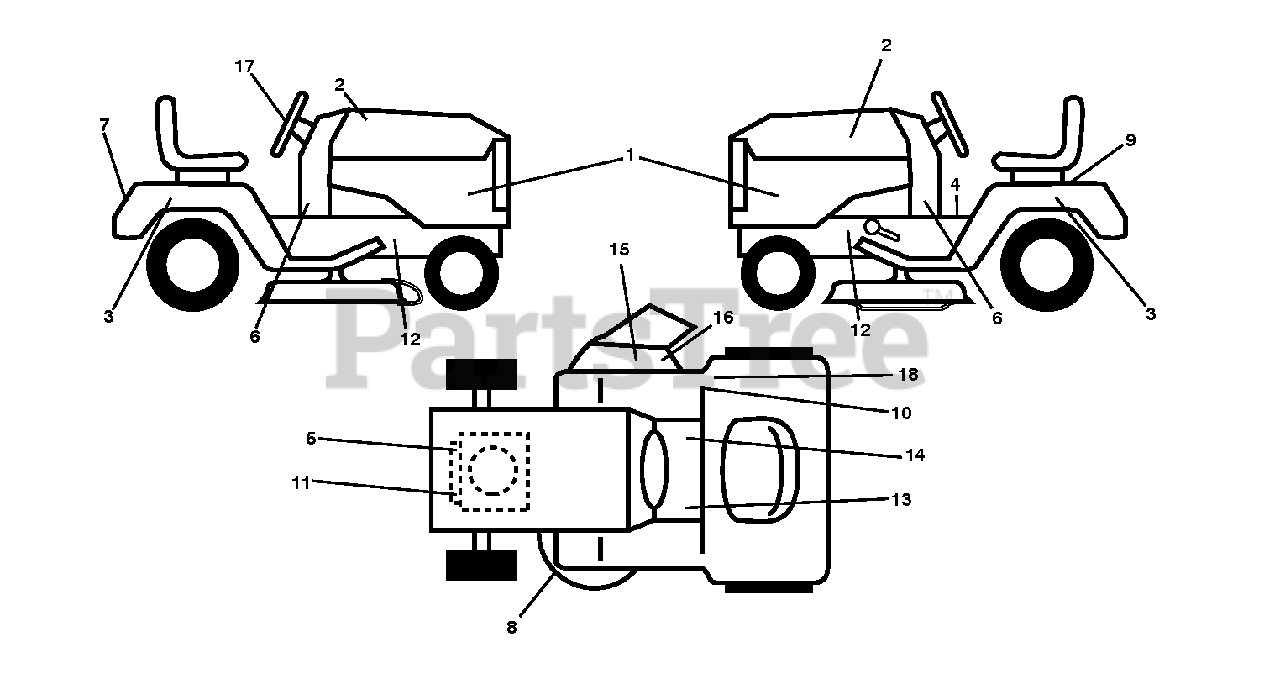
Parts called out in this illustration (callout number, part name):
5	DECAL.ENG.BS.5HP.PB.278978
6	DECAL.CHAS.TURBO
8	DECAL V BELT SCHEMATIC
9	DECAL BTRY SYMBOLS
10	DECAL 80 DBA
14	DECAL PARK BRAKE
15	DECAL.INTERNATIONL.CUTFINGER
16	DECAL, DEFLECT WARNING
